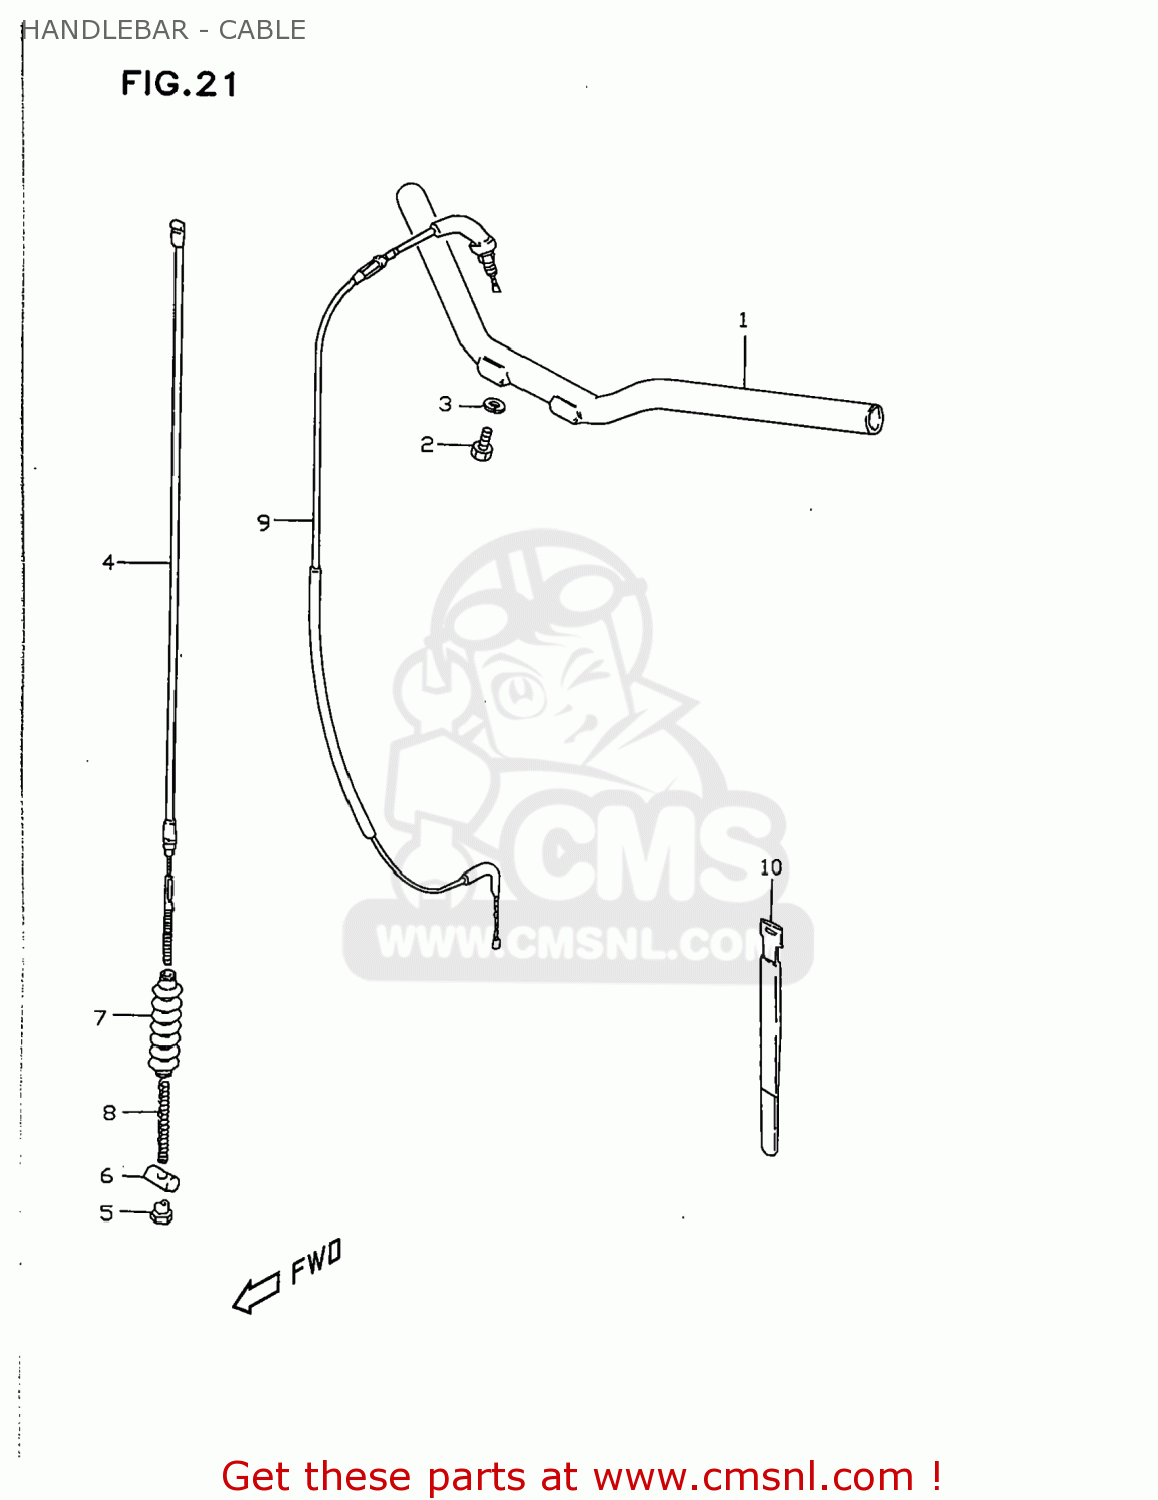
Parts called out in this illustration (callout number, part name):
1	HANDLEBAR
2	BOLT
3	LOCK WASHER
4	CABLE ASSEMBLY,FRONT BRAKE
5	NUT
6	PIN,10X19
7	SEAL,DUST(7X16X75)
8	SPRING
9	CABLE ASSEMBLY,THROTTLE
10	CLAMP(L:235)
